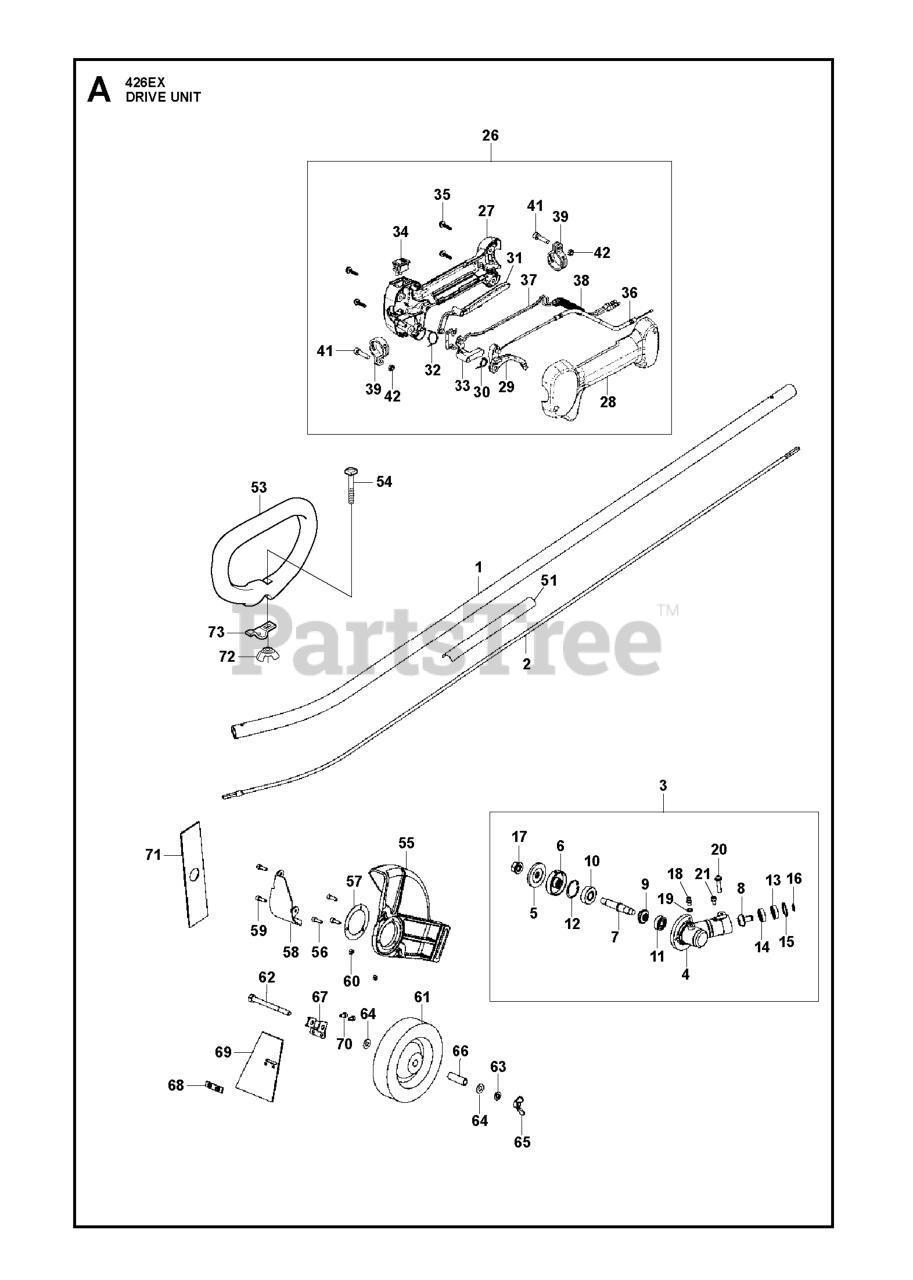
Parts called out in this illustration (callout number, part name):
2	FLEX SHAFT
7	SHAFT.GEAR
10	BEARING***
15	RP_RING
21	BOLT M5 X L10 ALLEN BOLT
27	BODY RIGHT
29	LEVER THROTTLE
30	SPRING, THROTTLE
31	LEVER SAFETY
32	SPRING JOINT
33	LEVER JOINT
41	BOLT
42	NUT
53	HANDLE, LOOP
56	BOLT M5 X L16 ALLEN
59	BOLT M5 X L16 ALLEN
70	BOLT M5 X L10 ALLEN BOLT
73	HOLDER
